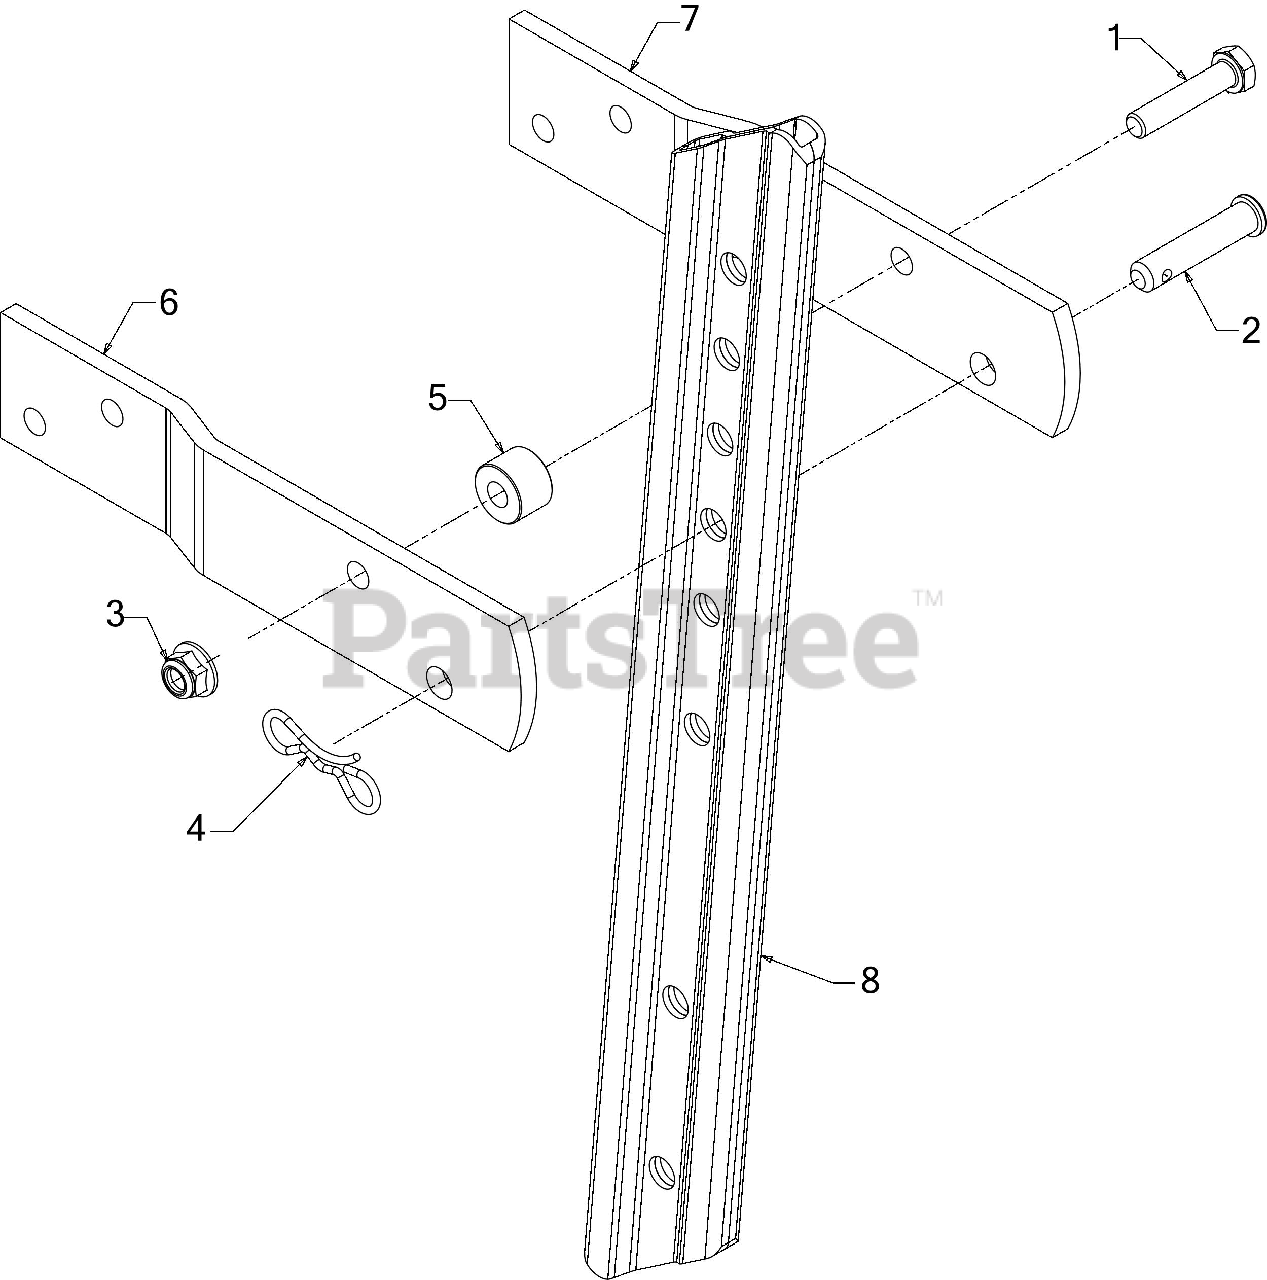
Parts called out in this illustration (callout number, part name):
1	SCREW 5/16-18 X 1.5 LG
2	CLEVIS PIN .375 X .1.75
3	FLANGE LOCK NUT 5/16-18
4	PIN:COTTER
6	TAILPIECE BRACKET
7	TAILPIECE BRACKET
